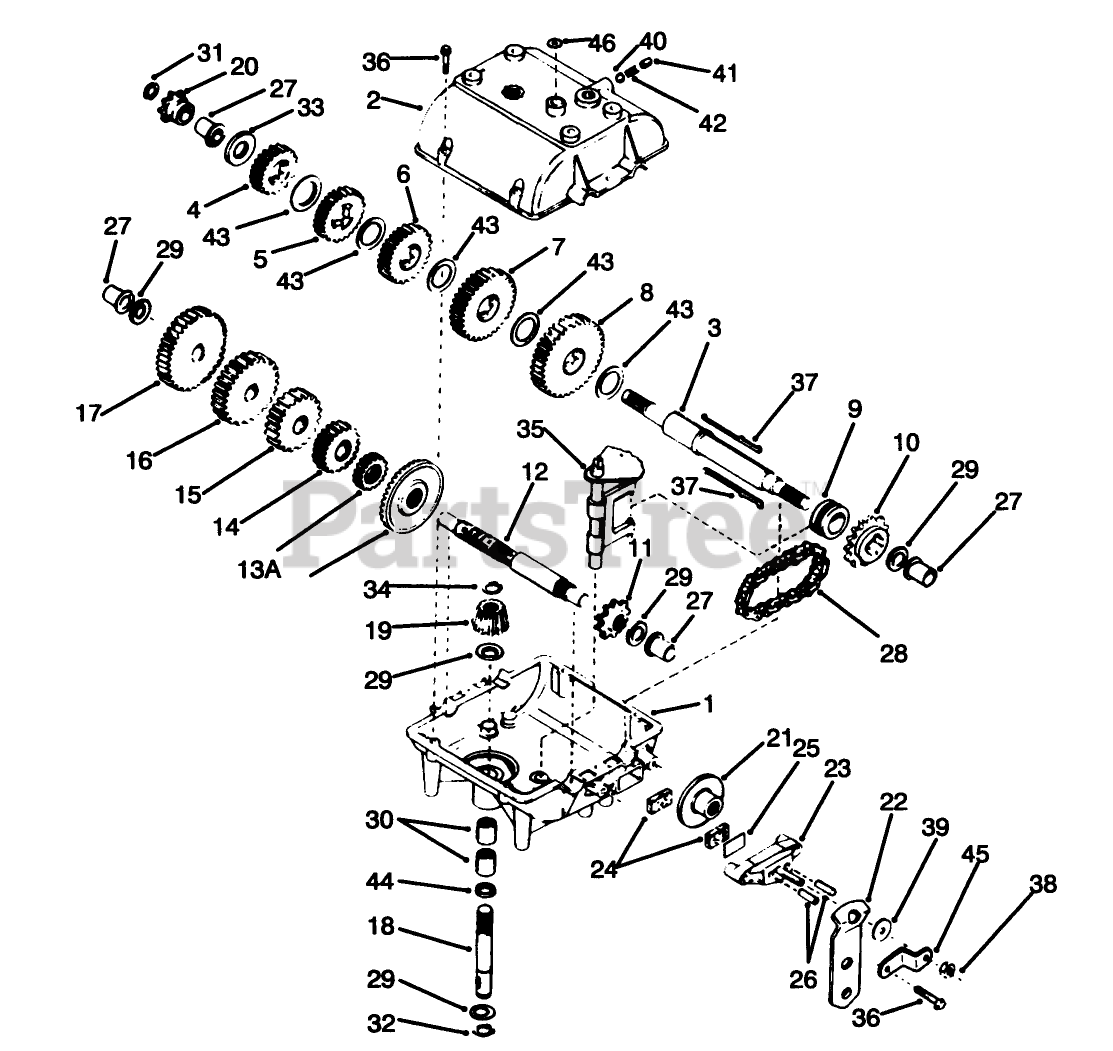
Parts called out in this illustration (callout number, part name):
1	Case-Transmission
2	Cover-Transmission
3	Shaft-Output
4	Gear-Spur 20 teeth
5	Gear-Spur (22 teeth)
6	Gear-Spur, 25 Teeth
7	Gear-Spur, 30 Teeth
8	Gear-Spur, 35 Teeth
9	Collar-Shift
10	Sprocket-18 Teeth
11	Sprocket-9 Teeth
12	Countershaft
13	Gear-Bevel (42 Teeth)
13A	Gear-Spur 15 Teeth
14	Gear-Spur, 20 Teeth
15	Gear-Spur, 25 Teeth
16	Gear-Spur (28 teeth)
17	Gear-Spur (30 teeth)
18	Shaft-Input
19	Bevel Pinion-Input
20	Sprocket (8Teeth)
22	Lever-Brake
23	Nozzle-Carburetor
24	Brake Pad
25	Brake Pad Plate
26	Dowel Pin
27	Bushing-Flange
28	Chain-Roller #41
29	Washer
30	Bearing-Needle
31	Piston Asm (.020 O S)
32	Ring-Snap
33	Washer
34	Ring-Retainer
35	Rod and Fork ASM
36	Ring Set (.020 O S)
38	Locknut
39	Washer
40	Ball-Steel
41	Screw-Set
42	Spring
43	Washer
44	O Ring
45	Bracket
46	Cut Seal-Square
